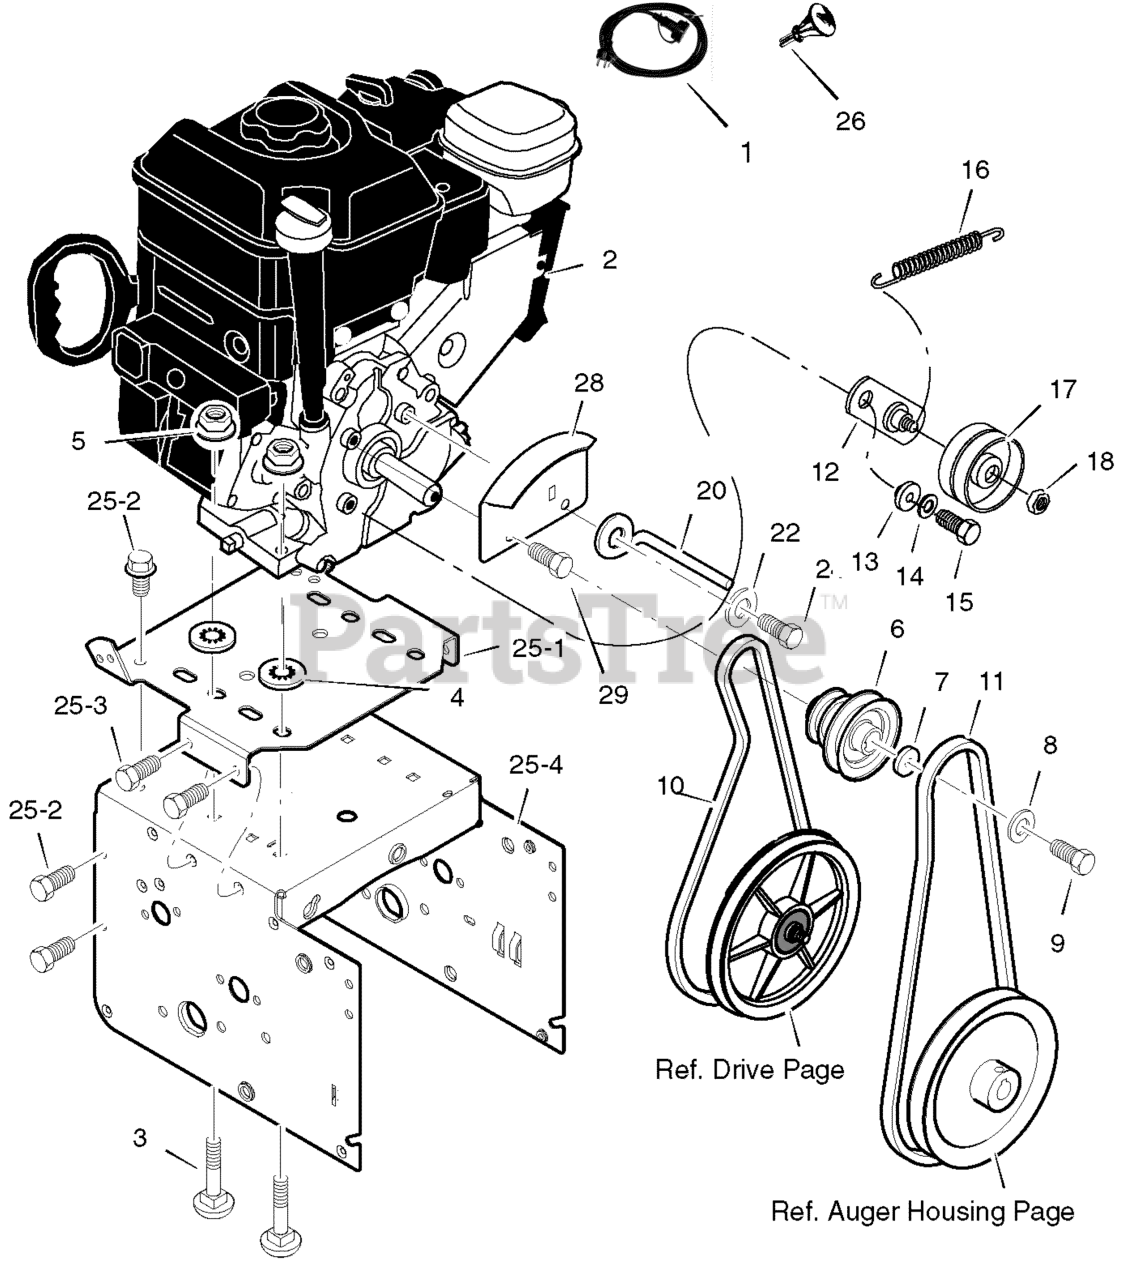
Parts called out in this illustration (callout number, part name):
1	CORD, ELECTRIC
2	ENGINE
3	BOLT, CARRIAGE
4	RETAINER, PUSH
6	PULLEY, ENGINE
7	WASHER
8	WASHER
9	SCREW
10	BELT, DRIVE V 3L
11	BELT, AUGER V 4L
12	BRACKET ASSEMBLY, IDLER
13	BUSHING, IDLER BRACKET
14	WASHER, SPLIT
15	SCREW 5/16-24 X 0.75
16	SPRING, IDLER TRACTION DRIVE
17	PULLEY, IDLER
18	NUT, JAM 3/8-16
20	GUIDE, ROD BELT
22	WASHER
25	FRAME ASSEMBLY
25-1	PLATE, ENGINE
25-2	SCREW
25-3	SCREW
25-4	MOTOR BOX
26	KEY, ENGINE
28	BRACKET, ENGINE SHIELD
